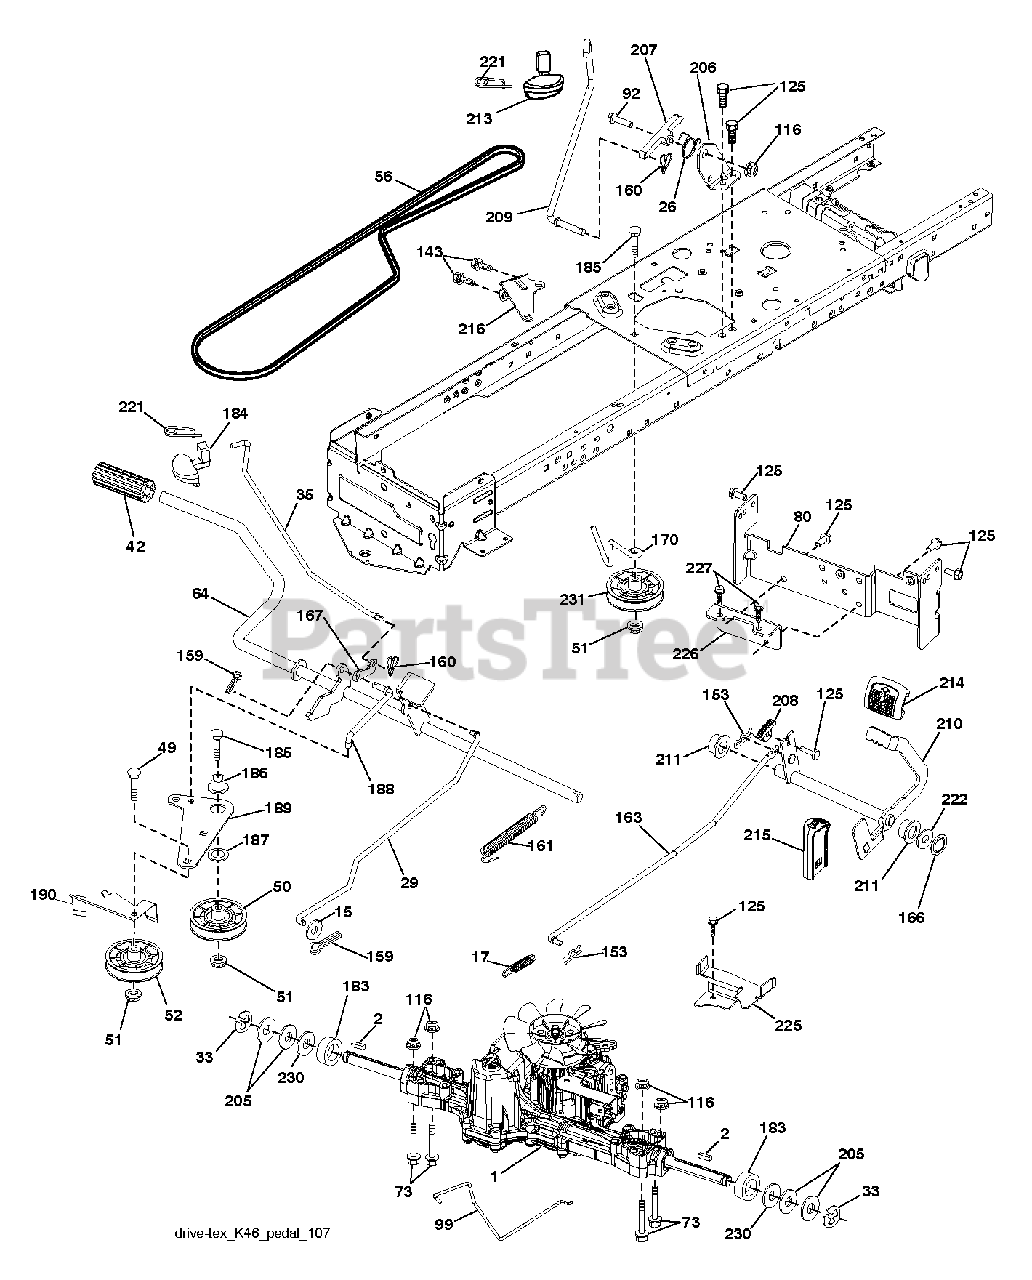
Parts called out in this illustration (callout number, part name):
2	SQUARE KEY
17	SPRING.BRAKE.K46.GREEN
26	SPRING.RETURN.CRUISE
29	ROD.BRAKE.K46
33	E-RING LT
35	ROD.BRAKE.PARKING.LT.T
49	BOLT
50	IDLER.FLAT.910.OFFSET
51	NUT LOCK FLG 3/8-16 UNC
52	IDLER.V-GROOVE.910.OFFSET
56	V-BELT.MOWER.92.40.42/K46
64	SHAFT.ASM.PEDAL.BRK.CNTR
73	BOLT
80	STRAP.TORQUE.K46.K57R.TT
92	BOLT
99	ROD.SPRING.BYPASS.K46.LT.Z
116	NUT LOCK HEX FLANGE 5/16-18
125	SCREW
143	SCREW LT
159	COTTER PIN
160	RETAINER CLIP
161	SPRING, RETURN LT
163	ROD.CONTROL.PEDAL.K46
166	NUT.PUSH.625
167	LATCH.BRAKE.SPRING
170	KEEPER.CENTER SPAN.1.688
183	SPACER AXLE
184	HANDLE.PARKING.BRAKE.LTTEX.667
186	SPACER.RETAINER
187	WASHER 12/32X2X10GA
188	LINK.CLUTCH.GROUND.DRIVE
189	BELLCRANK.GROUND.DRIVE.TEX.
190	KEEPER.BELLCRANK.DRIVE
206	BRKT.MOUNT.LATCH.CRUIS
207	LATCH.CONTROL.CRUISE
208	GEAR.SECTOR.CONTROL.CR
210	ROCKER.ASM.PEDAL.CONTR
211	BEARING.NYLON
213	HANDLE.CONTROL.CRUISE.ELTE
214	PEDAL.FORWARD.PAD.TEX
215	PEDAL.REVERSE.TEX.GT.4
216	BRACKET.PULLEY.IDLER.W/TEX
221	RETAINER.SPRING.CLIP.H
222	WASHER 21/32 X 1-1/4 X 10 GA.
225	KEEPER.BELT.TRANSAXLE.K46
226	BRACKET.MOUNT.TORQUE.K46.TLT
227	Screw, Lt
230	WASHER.HARDENED
231	IDLER.V-GROOVE.1.688.OFFSET
